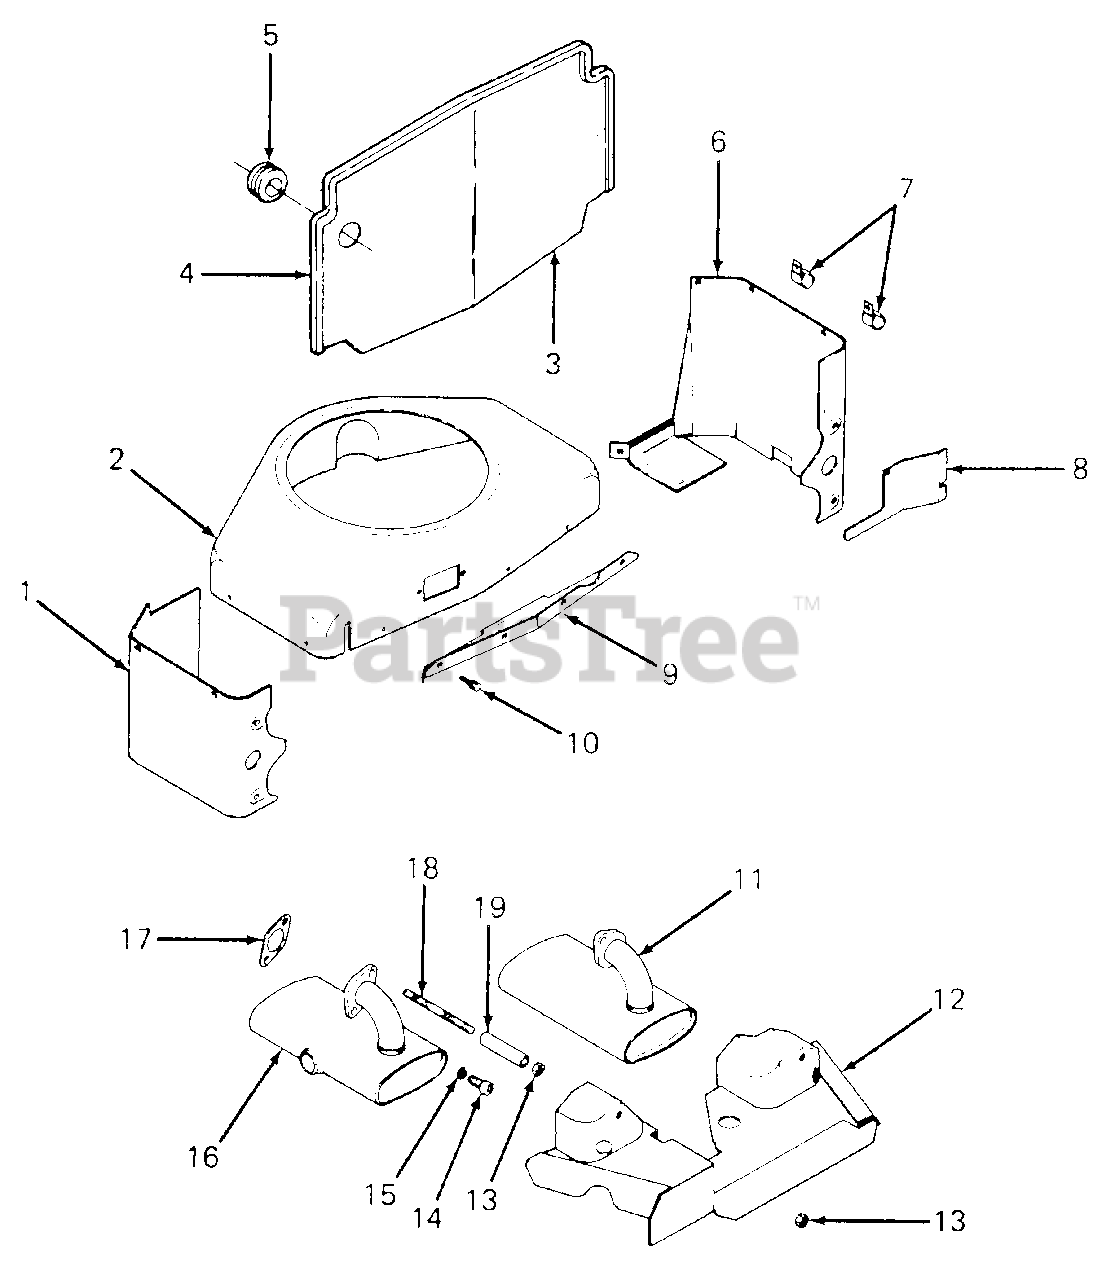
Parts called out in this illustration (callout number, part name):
1	Baffle, Cylinder Head, RH
2	Housing, Blower
3	Baffle, Engine Heat
4	Seal, Engine Heat Baffle
5	Bushing, Snap, 3/4
6	Baffle, Cylinder Head, LH
7	Clip
8	Top, Cylinder, LH
9	Support, Upper Housing
10	Screw, Hex Wash Hd, 1/4-20 X 7/16
11	Muffler, LH
12	Shield, Heat
13	Nut, Hex, 5/16-18
14	Screw, Hex Socket Hd, 5/16-18 X 3/4
15	Washer, Lock, 5/16
17	Gasket, Exhaust
18	Stud, 5/16-18 X 4
19	Spacer, 5/16 I.D. X 9/16 O.D.
